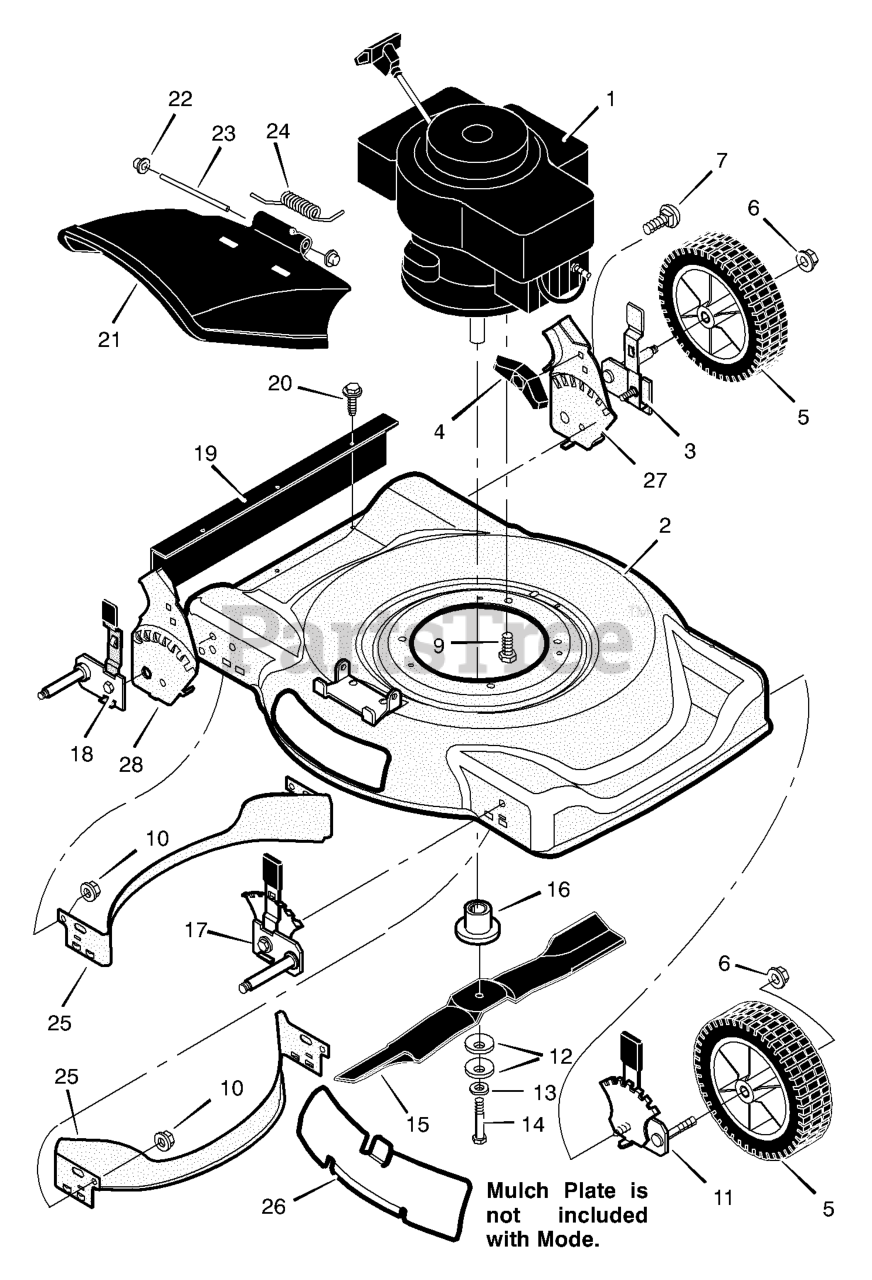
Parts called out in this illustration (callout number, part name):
1	Engine
2	Housing
3	Height Adjuster, Left Rear
5	Wheel and Tire
6	Locknut, Flange
7	Bolt, Carriage
9	Bolt, Engine
10	Nut
11	Height Adjuster, Left Front
12	Washer, Belleville
14	Bolt, Hex
16	Adapter, Blade
17	Height Adjuster, Right Front
18	Height Adjuster, Right Rear
19	Guard, Rear
20	Screw
21	Deflector, Chute
22	Push-On Cap
23	Pin, Pivot
24	Spring
25	Baffle
26	Plate,
27	Bracket, Left Handle
28	Bracket, Right Handle
